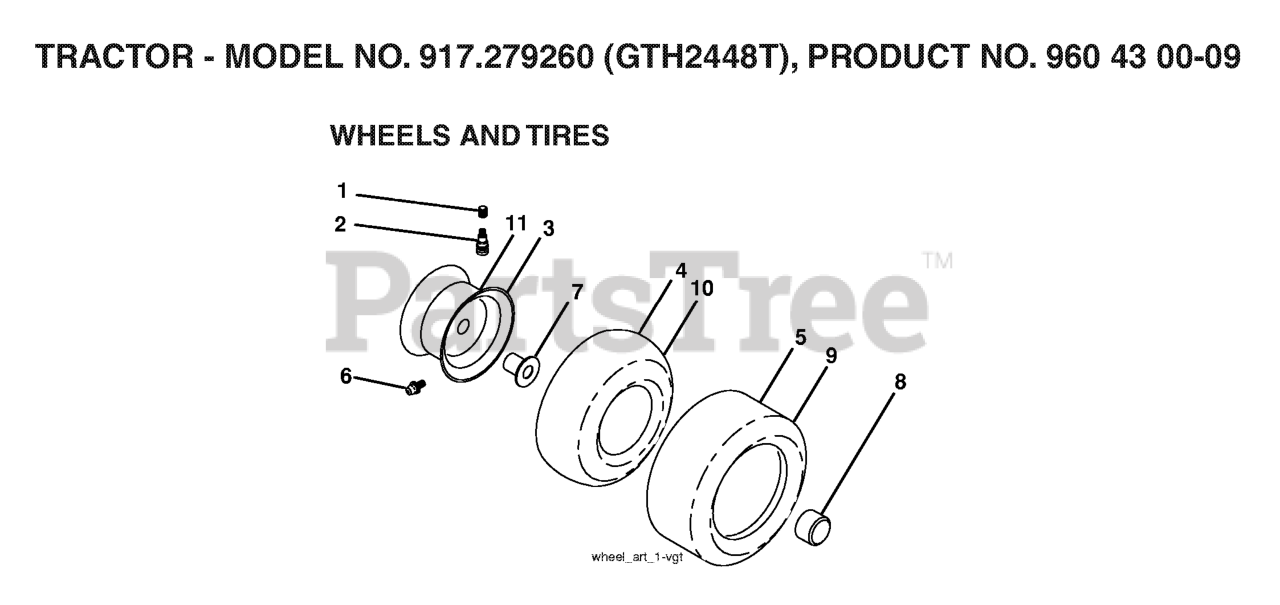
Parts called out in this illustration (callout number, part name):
2	VALVE STEM LT
3	RIM ASSEMBLY, FRONT
4	TUBE.5.3/4.5/6
5	TIRE HEAVY DUTY
6	FITTING LT
7	BEARING T
8	CAP, AXLE BLK
9	TIRE.22X9.50-12.TURF.SAVER.REA
10	TUBE
11	RIM.ASM.12".REAR.SILVER
